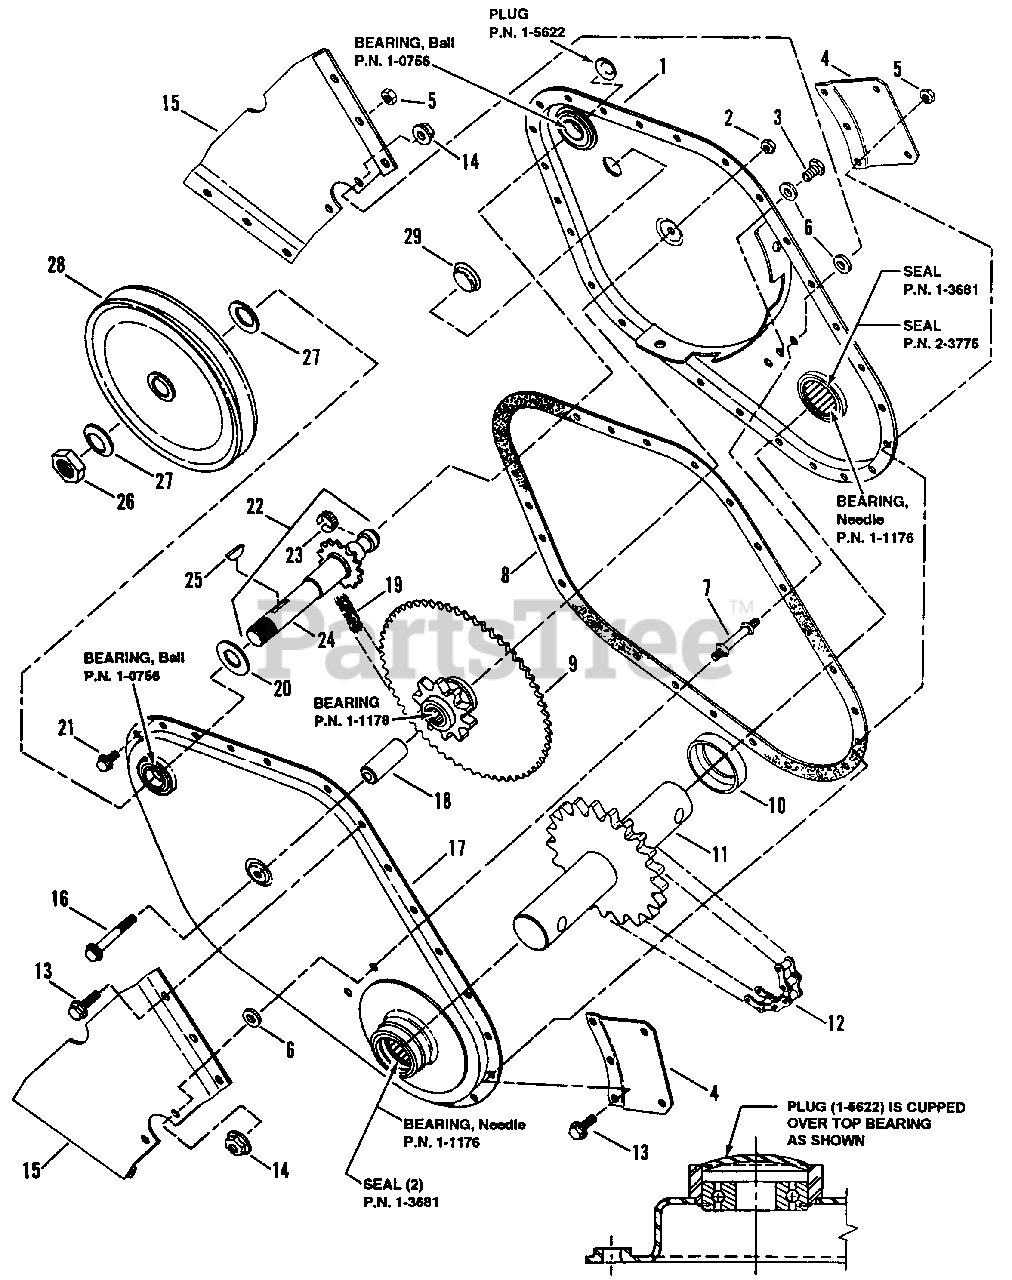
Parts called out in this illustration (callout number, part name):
1	ASSEMBLY, Chain Case (Right Hand)
2	NUT, 5/16-24 Hex Lock
3	SCREW, 5/16-18 x 3/8" Self-Tapping
4	RETAINER, Depth Bar
5	NUT, 5/16-18 Hex Lock
6	WASHER, Seal
7	STUD, Spacer 5/16 x 2.6
8	GASKET, Chain Case Housing
9	SPROCKET ASSM'Y., Intermediate
11	SHAFT, Tine Rotor
12	CHAIN, Drive (#50)
13	SCREW, 5/16-18 x 3/4" Hex Head Cap
14	NUT, 5/16-18 Hex Flange Lock
15	PLATE, Wear Guard
16	SCREW, 5/16-24 x 2 1/4" Hex Head Cap, Grade 5
17	(NLA) ASSEMBLY, Chain Case (Left Side)
18	RACE, Sprocket Bearing
19	CHAIN, Drive (#35)
20	WASHER, Shim .625 x .812 x .016
21	SCREW, 5/16-18 x 1/2" Self-Tapping
22	ASSEMBLY, Drive Shaft
23	RING, Tolerance .625
24	SHAFT, Drive
25	KEY, #9-3/16 x 3/4" Woodruff
26	NUT, 5/18-18 Hex Center Lock
27	WASHER, Cone .64 x 1.25 x .028
28	PULLEY, 6" O.D.
29	PLUG, 3/4"
